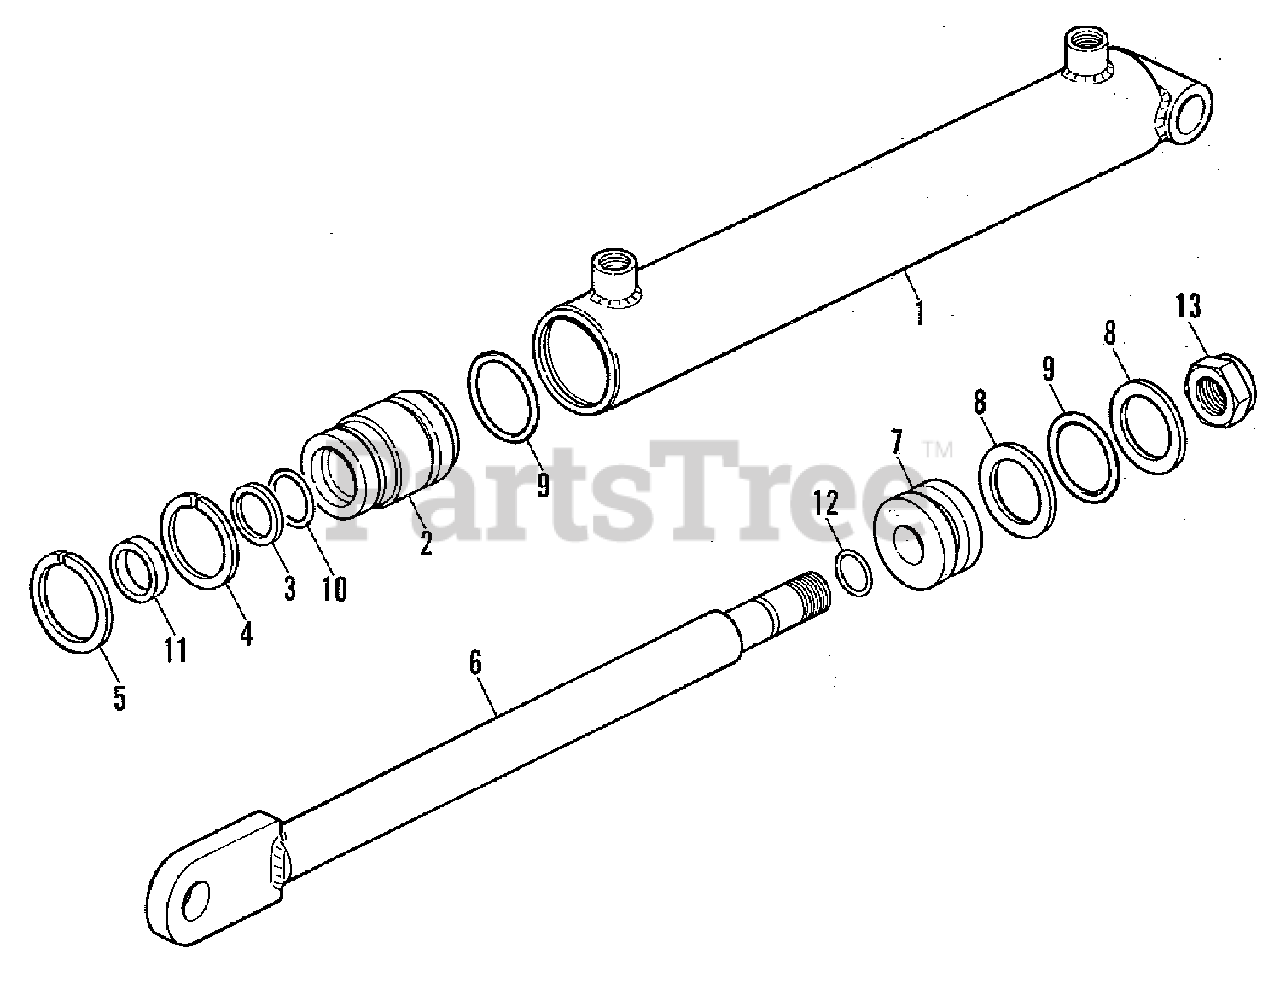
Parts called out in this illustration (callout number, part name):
1	BARREL ASSEMBLY
3	O-RING, Backup (Small)
4	RING, Snap (Gland)
5	RING, Snap (Barrel)
6	ROD ASSEMBLY
8	O-RING, Backup (Large)
9	O-RING, Gland & Piston Seal
10	O-RING, Rod Seal
11	SEAL, Rod Wiper
12	O-RING, Rod Static
13	NUT, Lock, 1/2NF
